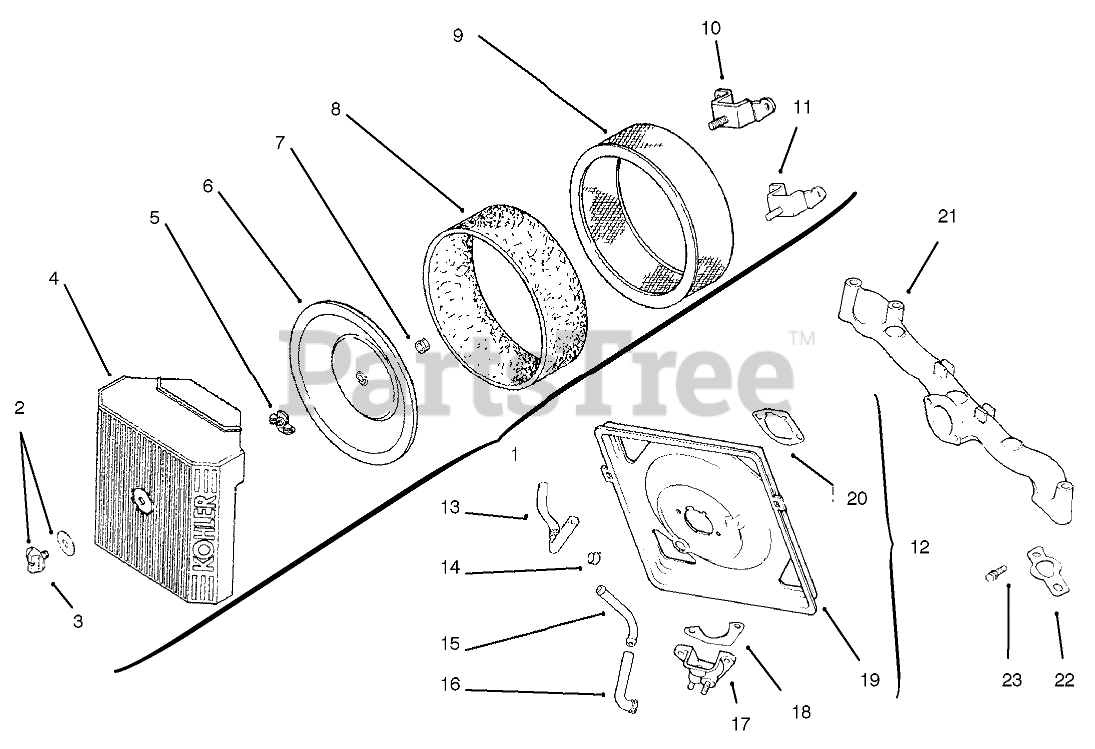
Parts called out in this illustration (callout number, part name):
1	Kit-Air Cleaner Cover
2	Kit-Knob w/Gasket
3	Knob-Cover
4	Cover-Air Cleaner
5	Wingnut
6	Cover-Inner AirCleaner
7	Seal, insert
8	Bement-Precleaner
9	Bement-Air Cleaner
10	Bracket-Air Cleaner
11	Bracket-Air Cleaner
12	Kit-Air Cleaner Base
13	Hose-Breather
14	Clamp
15	Fitting
16	Hose-Breather
17	Cup-Fuel Spitback
18	Gasket-Fuel Spitback
19	Base-Air Cleaner
20	Gasket-A/C Base
21	Manifold-Intake
22	Gasket-Intake, Manifold
23	Screw
